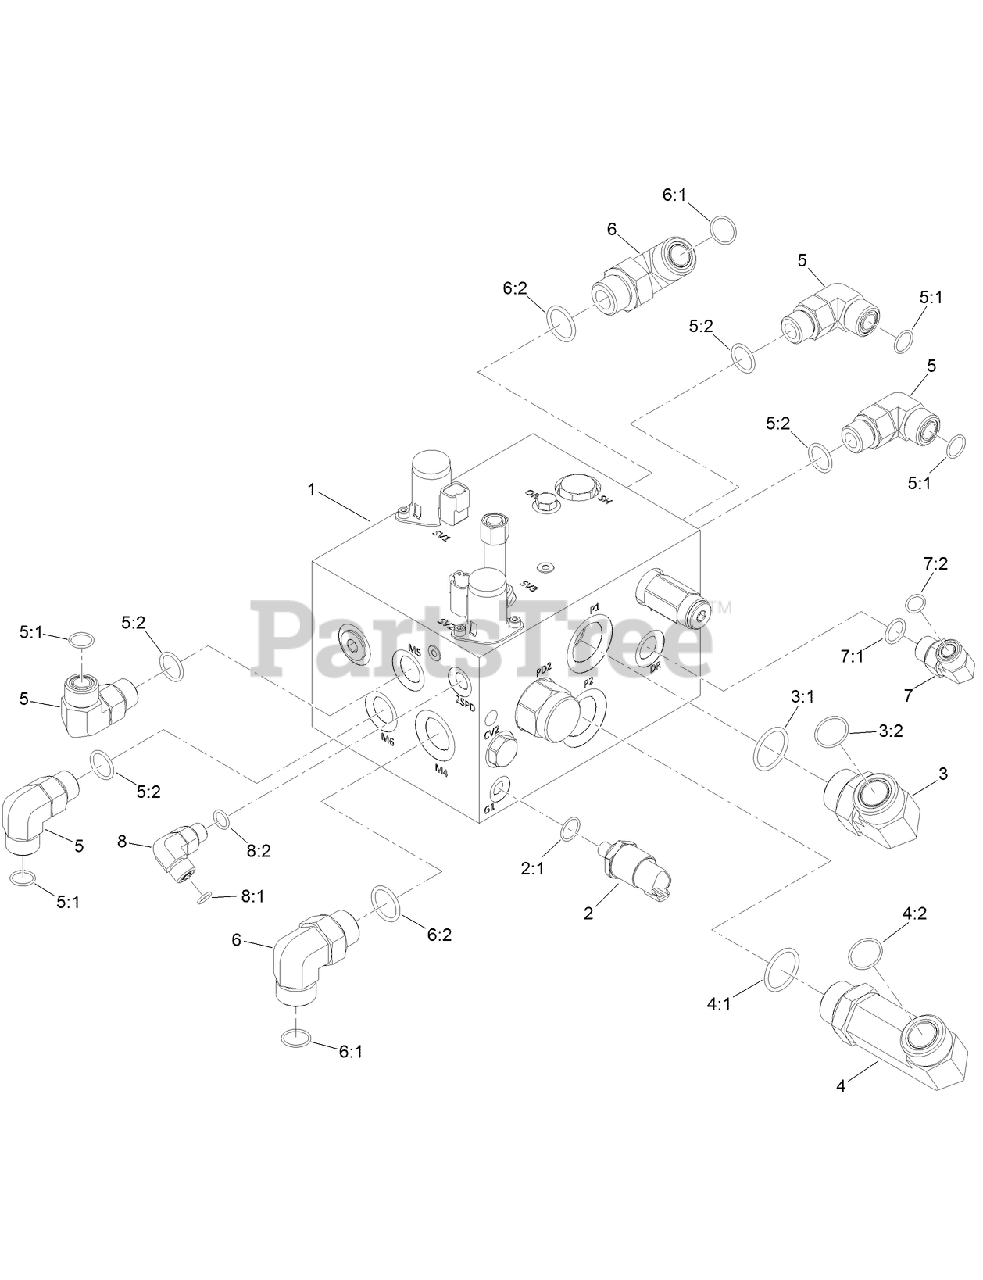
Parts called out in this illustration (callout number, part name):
1	THRUST MANIFOLD ASM
2	TRANSDUCER
2:1	O-RING
3	FITTING-ELBOW, 90 DEG
3:1	O-RING
3:2	O-RING
4	FITTING-ELBOW, 90 LONG
4:1	O-RING
4:2	O-RING
5	FITTING-ELBOW, 90 DEG
5:1	O-RING
5:2	O-RING
6	FITTING-ELBOW-90
6:1	O-RING
6:2	O-RING
7	FITTING-ELBOW, 90 DEG
7:1	O-RING
7:2	O-RING
8	FITTING-ELBOW, 90 DEG
8:1	O-RING
8:2	O-RING
